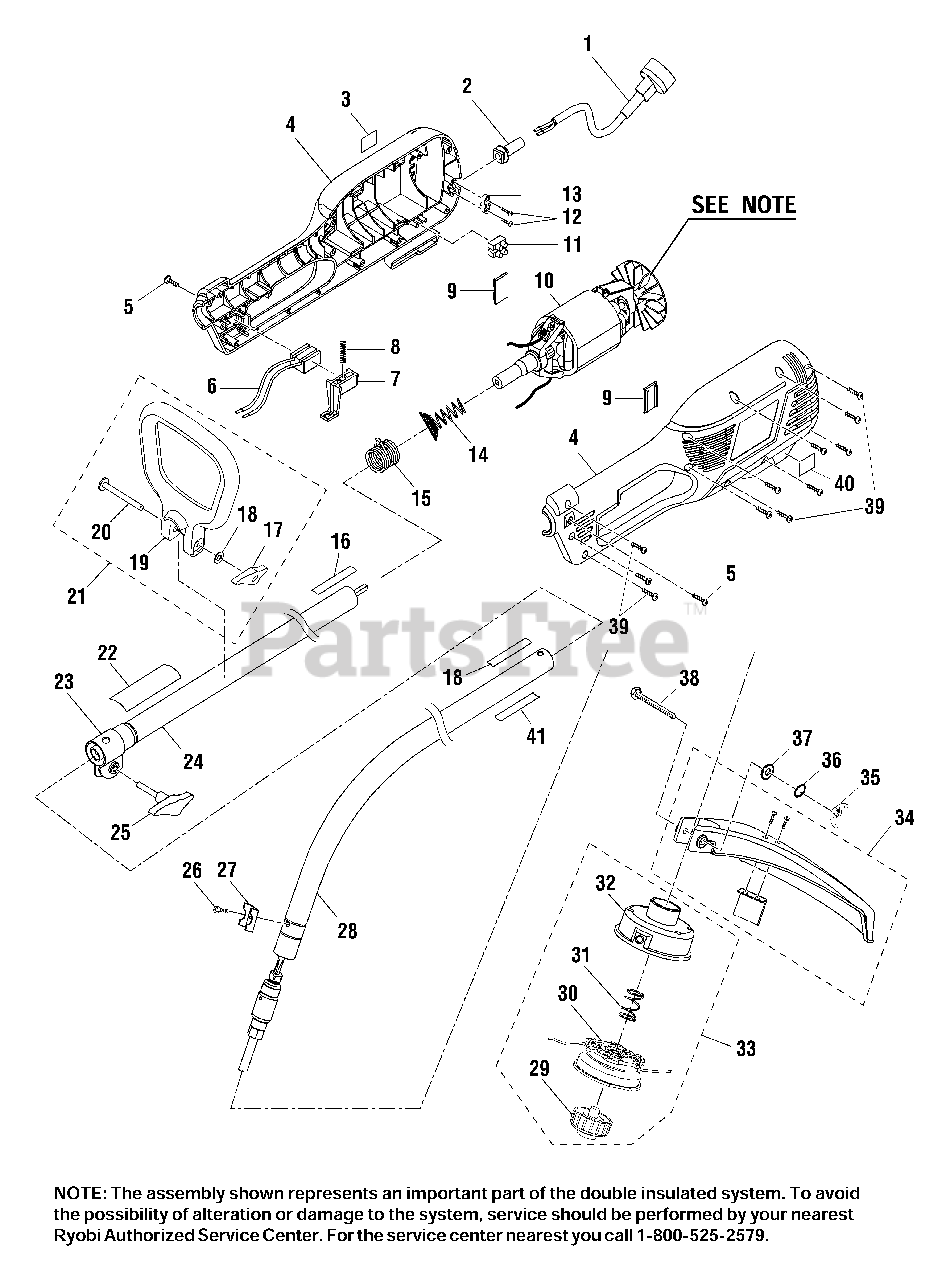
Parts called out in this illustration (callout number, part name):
2	BEND RELIEF
3	DATA PLATE
4	HOUSING ASSEMBLY
5	SCREW (M4 X 10 mm)
6	SWITCH ASSEMBLY
7	SWITCH TRIGGER
9	RUBBER CUSHION
10	MOTOR ASSEMBLY
11	CONNECTOR ASSEMBLY
12	SCREW (M4 X 15 mm)
19	FRONT HANDLE
20	CARRIAGE BOLT (M6 X 50 mm)
21	AUXILARY HANDLE ASSEMBLY
22	WARNING LABEL
23	EXPAND-IT COUPLER
24	ALUMINUM BOOM ASSEMBLY
25	KNOB
26	SCREW (M5 X 8 mm)
27	GRASS DEFLECTOR CLAMP
28	LOWER DRIVE SHAFT HOUSING ASSEMBLY
29	RETAINING CAP
30	SPOOL WITH LINE
31	COMPRESSION SPRING
32	TRIMMER HEAD WITH EYELETS
33	STRING HEAD ASSEMBLY
34	GRASS DEFLECTOR ASSEMBLY
35	WING NUT (1/4 in.)
36	SPRING WASHER
37	WASHER
38	HEX BOLT (1/4 in.)
39	SCREW (M4 X 18 mm)
40	LOGO PLATE, LEFT HOUSING
41	LOWER BOOM WARNING LABEL
